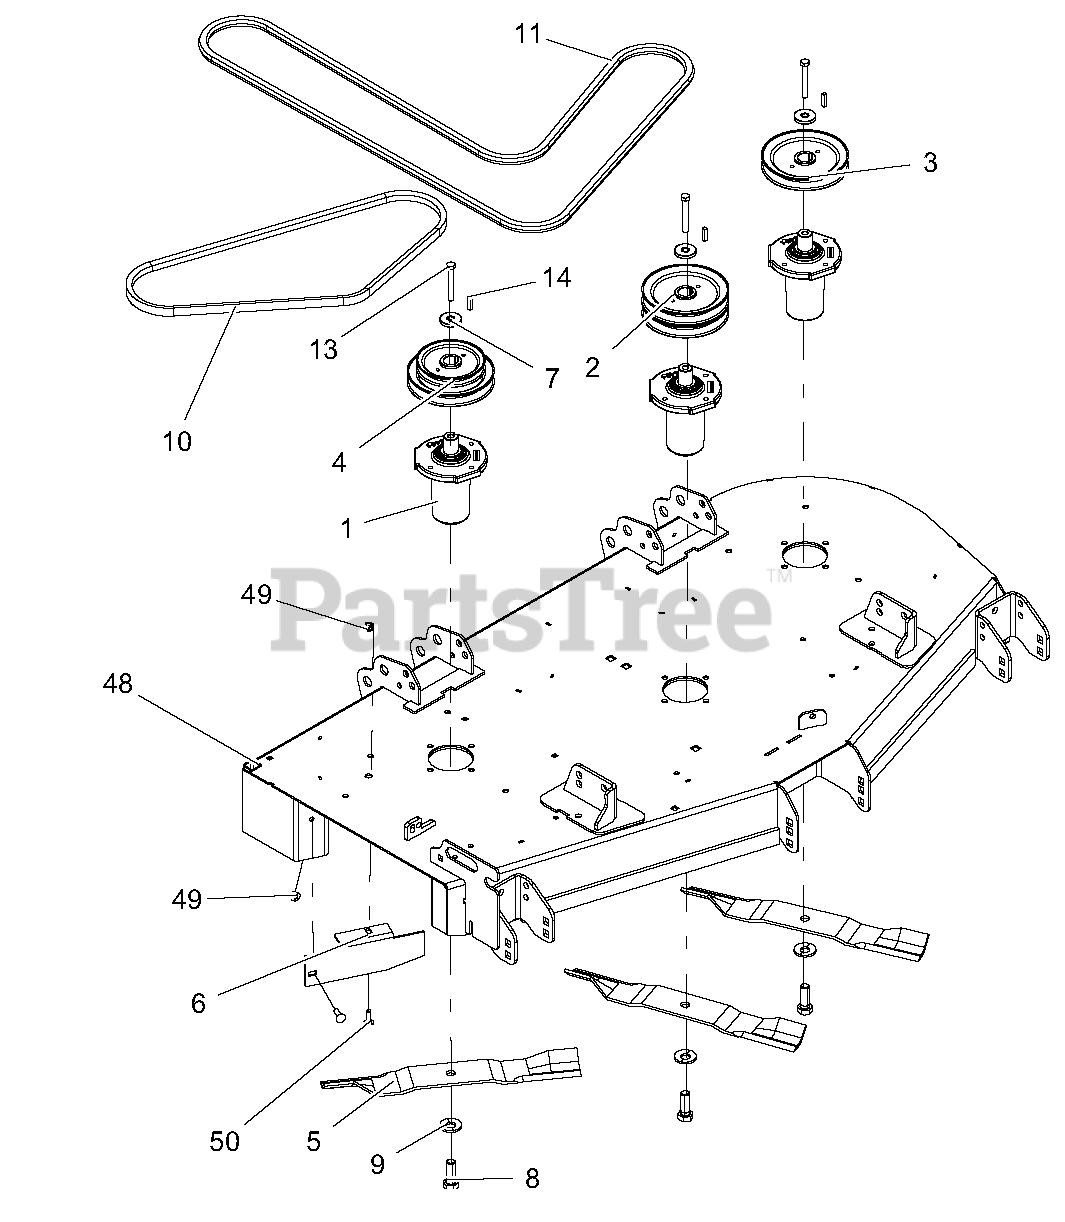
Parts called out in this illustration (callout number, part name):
1	SERVICE, ASM, SPINDLE - DUCTILE
2	PULLEY, DOUBLE -1" ID X 6.00" OD-BLACK (SN 000101 - 020999)
3	PULLEY, SINGLE -1" ID X 6.00" OD-BLACK
4	PULLEY, DOUBLE -1" ID X 6.00" & 4.75" OD
5	BLADE, 18"
6	BAFFLE, DISCHARGE, 52"-RED
7	RETAINER, SHEAVE SPINDLE
8	BLT, HEX .62-18X1.75 GR8 YWZC
9	WSHR, BLVL .63X1.625X.14
10	BELT, B 56.00 RAW COGGED
11	BELT, BB 118.00 WRAPPED HEX
13	BLT-HEX .38-16X2.75 GR8 YWZC
14	KEY-SQ .250X.250X1.00 RC 40-50
48	WLDMT, 52" SIDE DISCH DECK-RED
49	NUT-LK-NYL-FLG .31-18 YWZC
50	@BLT-RDHDSQSHNK .31-18X1.00 G5 Y
